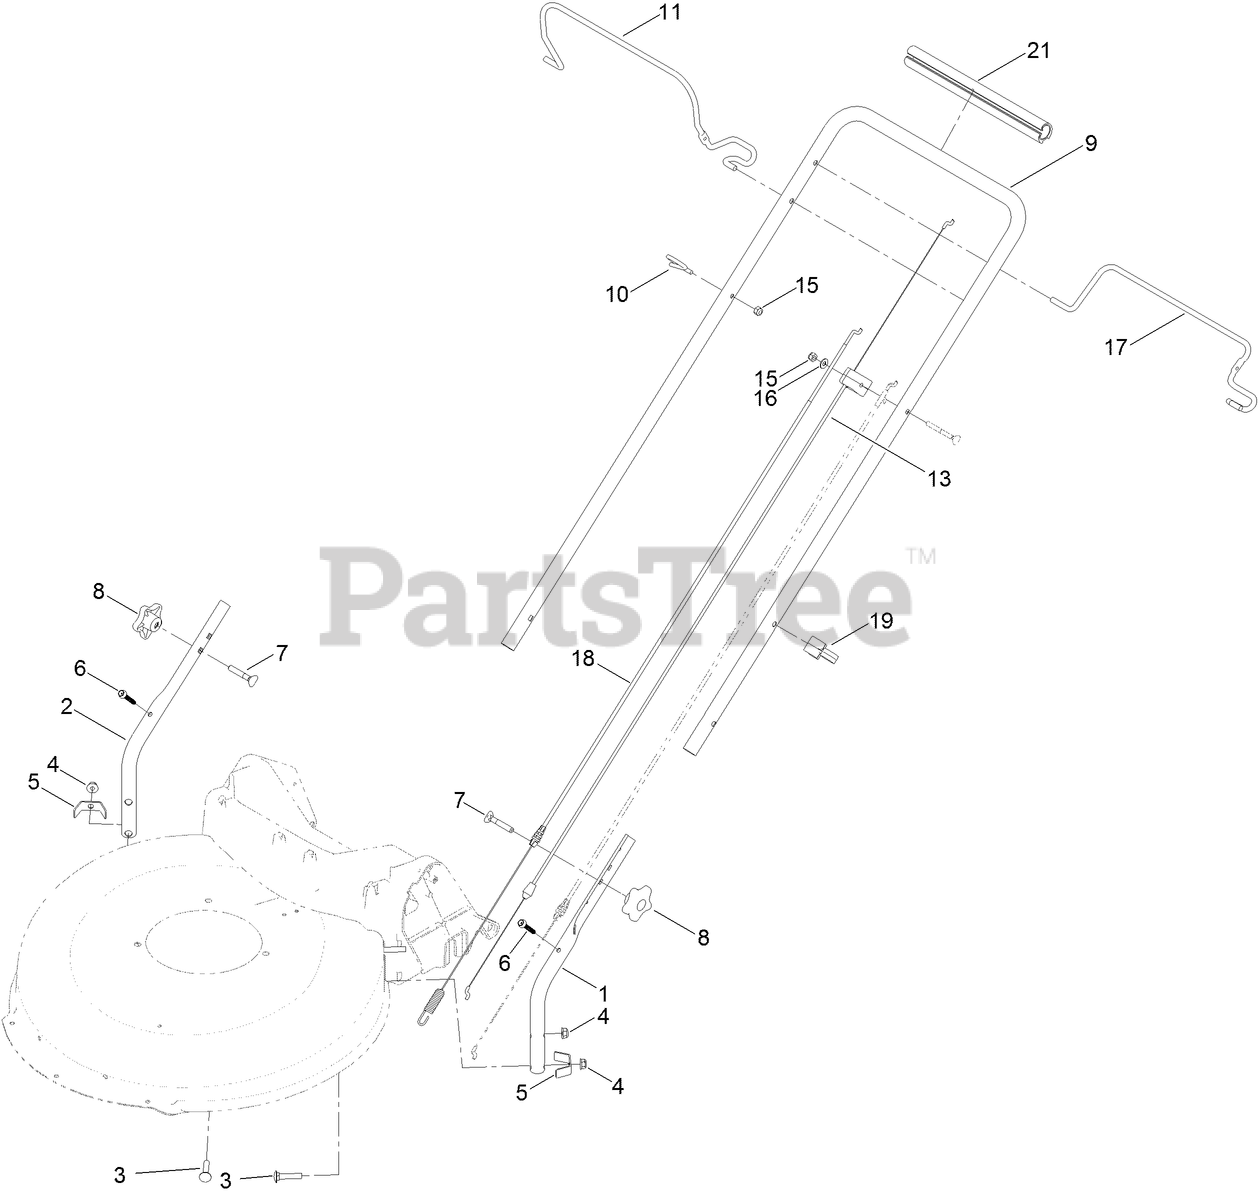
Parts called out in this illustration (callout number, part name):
1	HANDLE-LOWER, LH
2	HANDLE-LOWER, RH
3	BOLT-CARR
4	NUT-FLANGE, NI
5	BRACKET-CHUTE
6	SCREW-FLANGE, SERRATED
7	SCREW-HANDLE
8	KNOB-HANDLE
9	HANDLE-UPPER
10	GUIDE-ROPE
11	BAIL-BRAKE
13	CABLE-BRAKE
15	NUT-LOCK, NI
16	WASHER-FLAT
17	BAIL-TRACTION
18	CABLE-TRACTION
19	GUIDE-CABLE
21	GRIP-HANDLE, COMFORT
